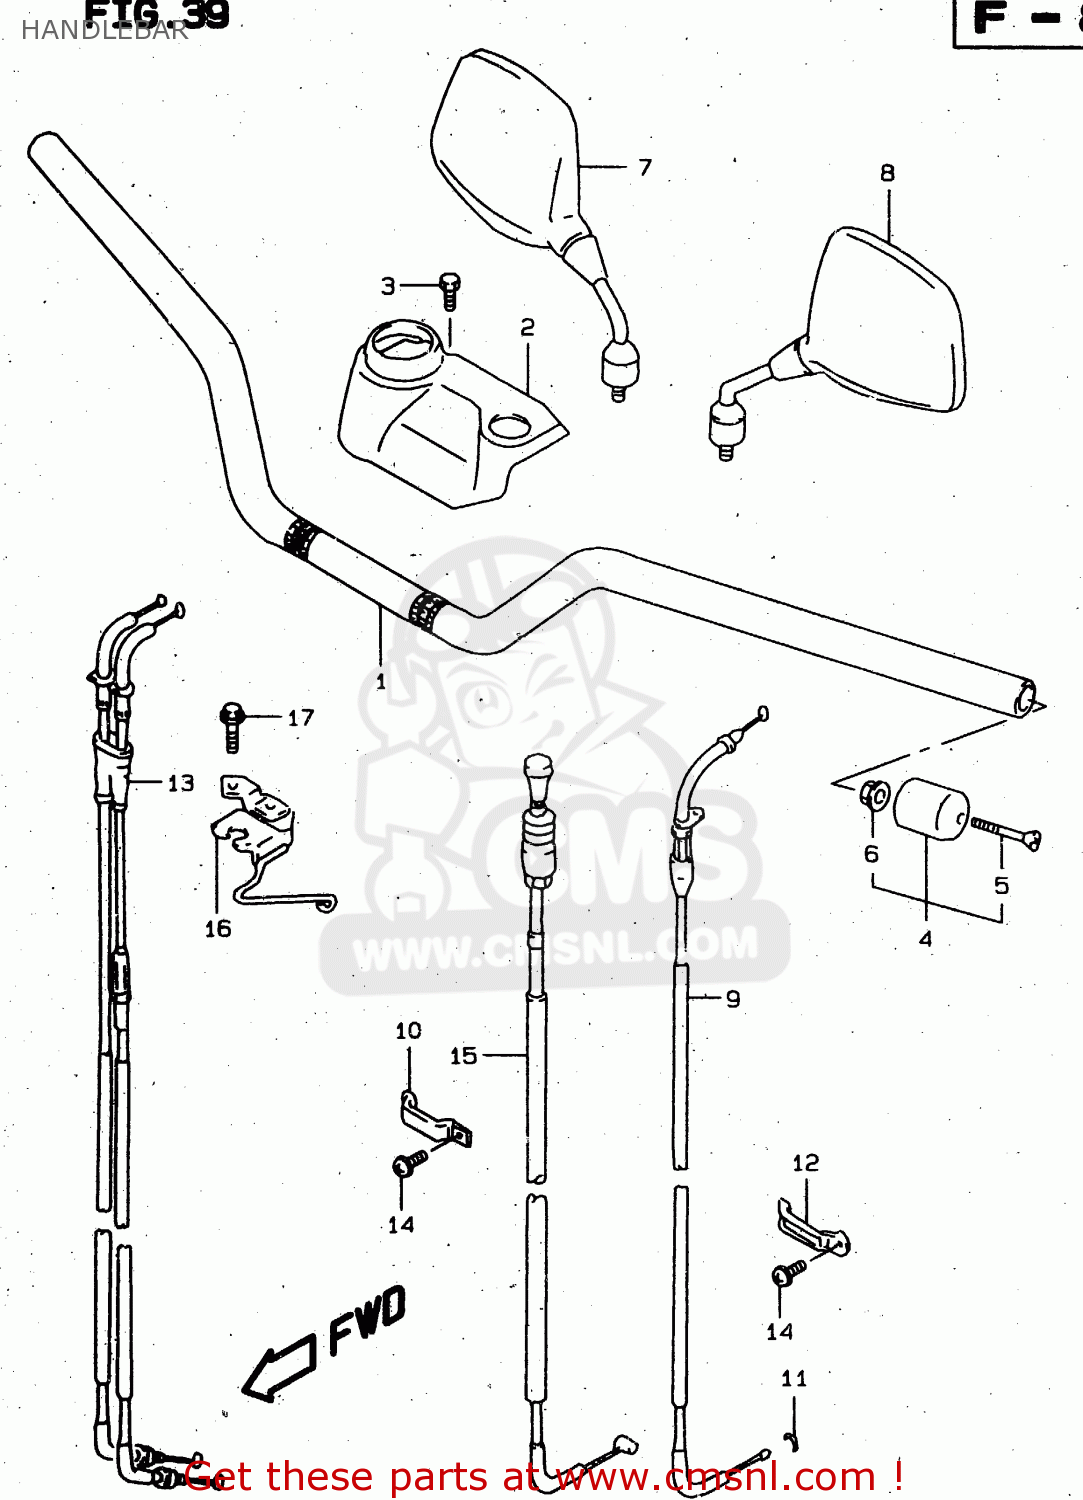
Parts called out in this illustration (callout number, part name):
1	HANDLEBAR
2	COVER,STEERING HEAD
3	SCREW(6X12)
4	BALANCER SET,HANDLEBAR
5	SCREW
6	NUT
7	MIRROR ASSY,RR VIEW,R
8	MIRROR ASSY,RR VIEW,L
9	CABLE ASSY,CLUTCH
10	CLAMP
11	STOPPER,CLUTCH CABLE
12	CLAMP
13	CABLE ASSY,THROTTLE
14	BOLT
15	CABLE ASSY,STARTER
16	BRACKET,STARTER CABLE
17	BOLT
